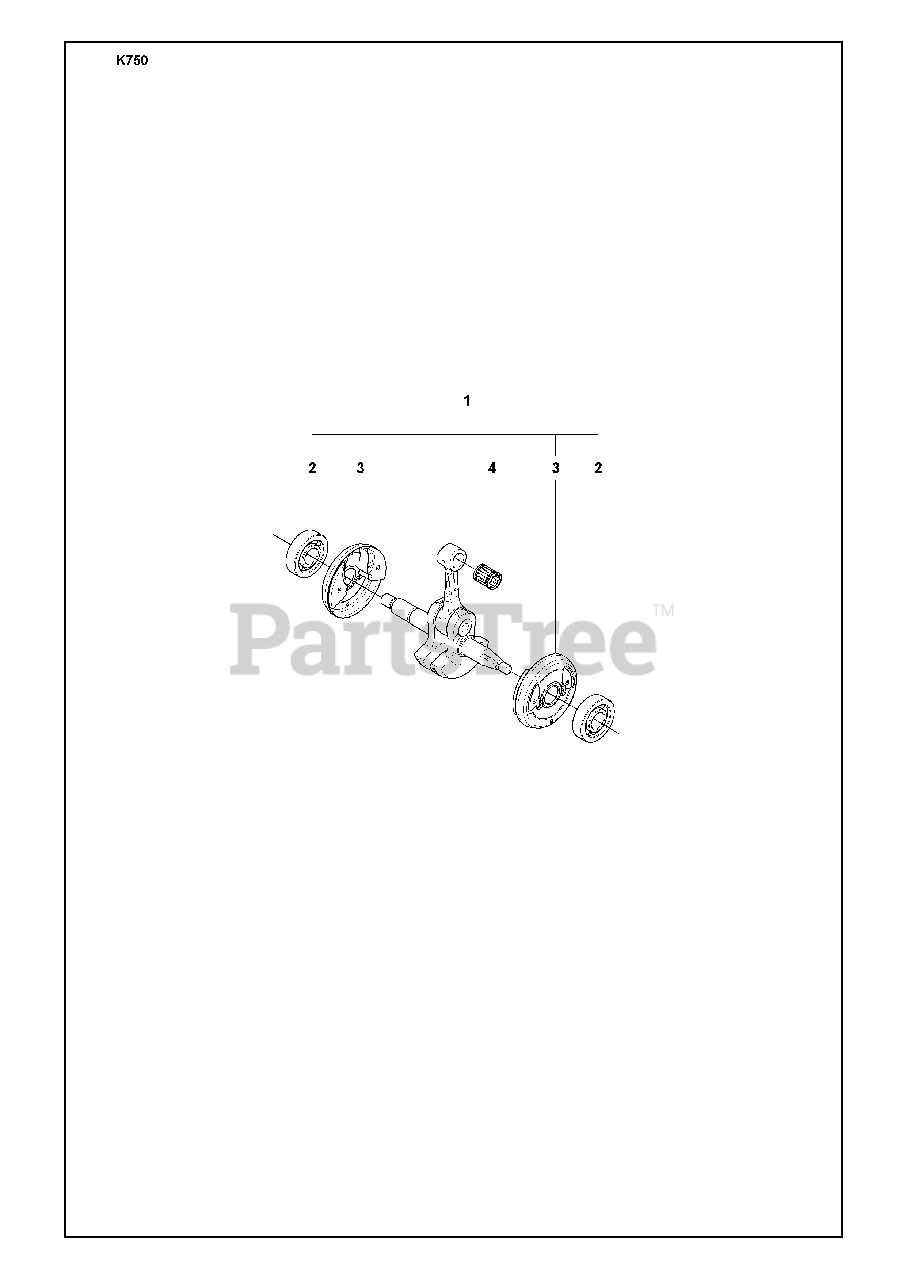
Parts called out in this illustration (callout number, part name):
1	CRANKSHAFT ASSY
2	BALL BEARING
4	NEEDLE BEARING
